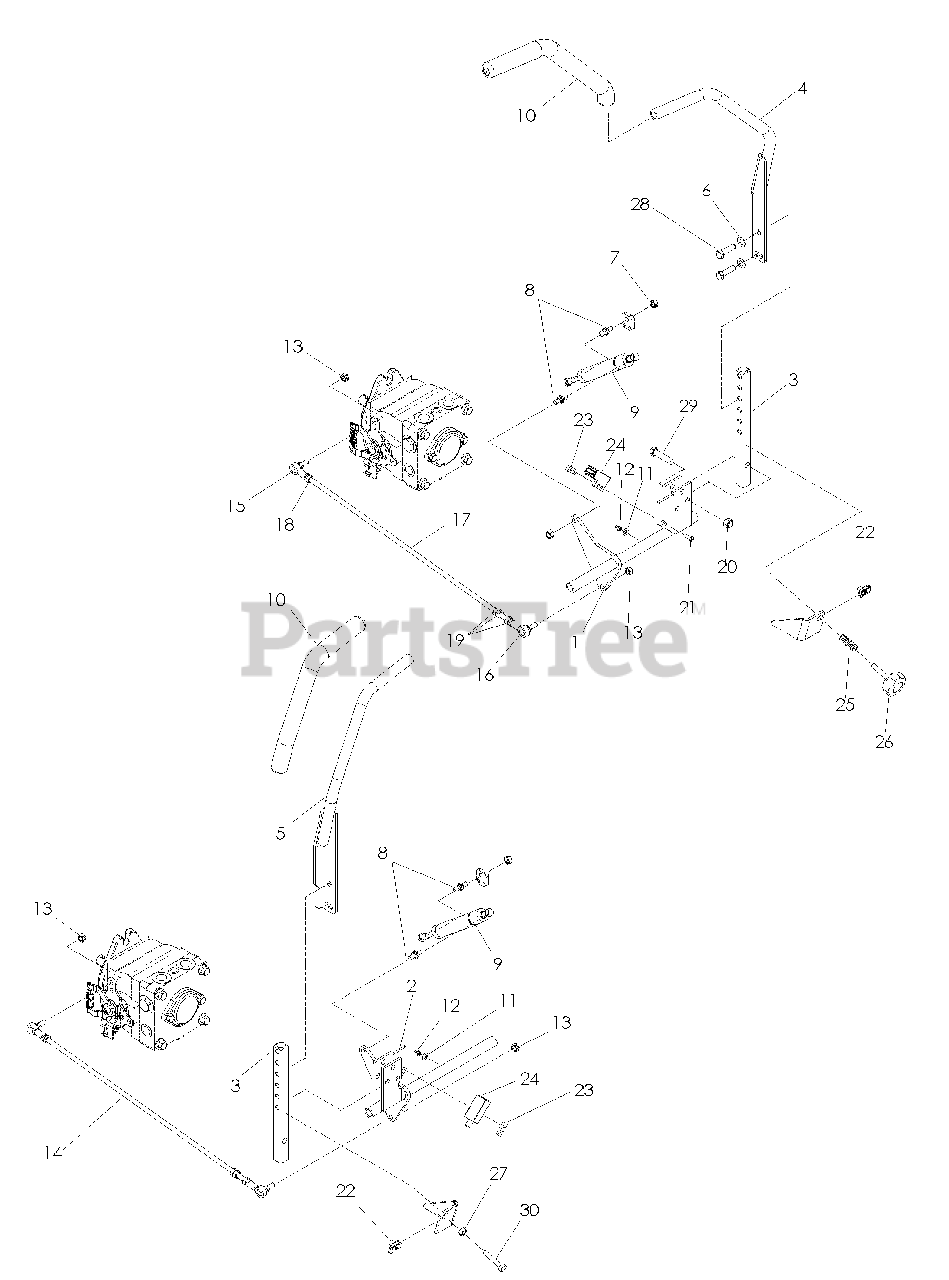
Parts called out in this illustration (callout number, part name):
1	CONTROL, LT
2	CONTROL, RT
3	ARM, CONTROL SHAFT
4	DRIVE LEVER, LT
5	DRIVE LEVER, RT
6	WASHER 3/8 SPRING
7	NUT 5/16-18 HEX CTRLK
12	ZERK
13	NUT 5/16-24 NYLOC
15	SPHERICAL ROD END LH
16	SPHERICAL ROD END RH
18	NUT 5/16-24 HEX JAM LH
19	NUT 5/16-24 HEX
20	NUT 3/8-16 HEX NYLOC
21	SCREW #10-24 x .625
22	RETAINER, 5/16-18 U-TYPE
23	TAPPED PLATE
26	TRACKING KNOB
27	NUT 5/16-18 HEX
28	HCS 3/8-16 x 1
29	HCS 3/8-16 x 1 3/4
30	HCS 5/16-18 x 1 3/4 TPBLT
